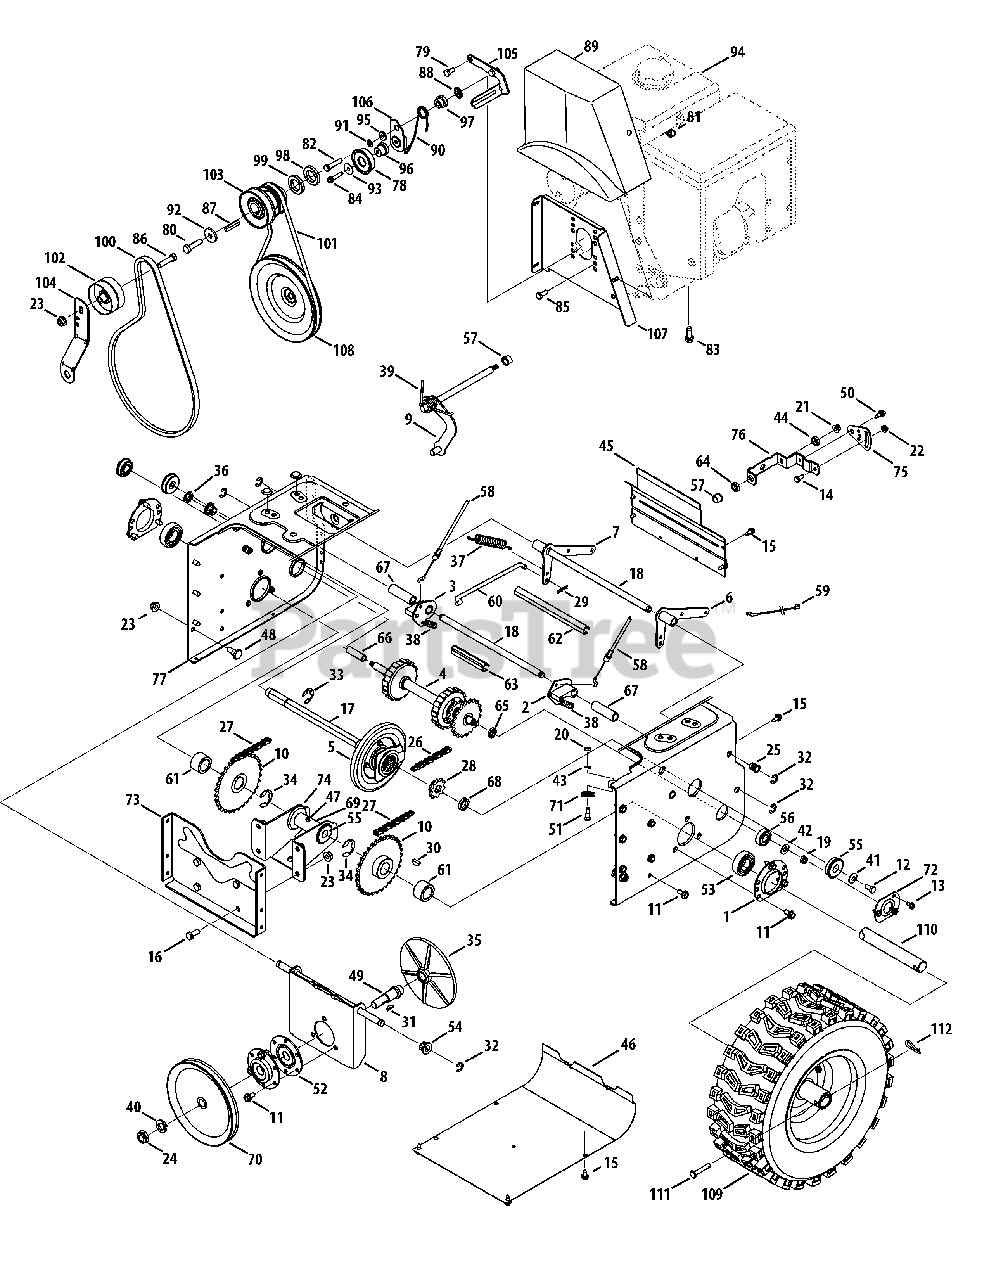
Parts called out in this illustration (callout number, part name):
1	Housing, Bearing
2	Dogg, Steering Drive, LH
3	Dogg, Steering Drive, RH
4	Shaft Assembly, Steering
5	Assembly, Friction Wheel
5	Wheel, Friction, Bonded
5	Screw, Hex Wash
6	Bracket, Auger Actuator
7	Bracket, Drive Actuator
8	Brkt, Friction Drive Suprt.
9	Rod Assembly, Shift
10	Sprocket, 32T
11	TT Screw, 5/16-18 x .750
12	Screw, Hex Cap Lock,
13	1/4-20 x .50
14	Hex Head Screw, 1/4-20
15	Screw, Hex Wash.
16	Screw, Hex Cap, 3/8-16
17	Shaft, Hex Drive
18	Shaft, Actuator
19	Nut, Hex Insert Jam Lock
20	Nut, Hex, 1/4-28 GR5
21	Flange Lock Nut, 5/16-18
22	Flange Lock Nut, 1/4-20
23	Flange Lock Nut, 3/8-16
24	Hex Nut, 5/8-18
25	Nut, Insert 3/8-16
26	Chain, Endless, #41 x 36L
27	Chain, #420 x 40L
28	Sprocket, #41 x 10T
29	Pin, Internal Cotter
30	Key, Woodruff
31	Key, Hi-Pro, 3/16 x 5/8
32	E-Ring
33	Ring, Retaining
34	Ring, Retainer
35	Plate, Drive
36	Speed Nut, .500
37	Spring, Extension
38	Spring, Extension
39	Torsion Spring, .750 I.D. x .968 Lg.
40	Washer, Lock, 5/8
41	Wsh, Bell., .34 x .872 x .06
42	Wash, .406 x .875 x .059
43	Washer, Lock, 1/4
44	Flat Washer, .469 x .875 x .105
45	Cover, Upper Frame
46	Cover, Lower Frame
47	Fitting, Lube, 3/16 Drive
48	Screw, Shldr., .498 x .34
49	Spindle, Drive Plate
50	Shoulder Screw, .368 x .113, 1/4-20
51	Screw, Hex Shldr., 1/4-28
52	Ass’y, Bearing/Housing
53	Bearing, Self Aligning
54	Bearing, Hex Flange
55	Bearing, Ball
56	Bush, Flg, .5625 x 1.375 x .4375
57	Bush, Flg, .5 ID x .627 OD
58	Steering Cable, 35.97" Long
59	Cable, Auger Idler
60	Rod, Drive Clutch
61	Spcr., 1.0 ID x 1.50 OD
62	Spcr., .51 ID x 7.895 Lg.
63	Spcr., .51 ID x 3.66 Lg.
64	Spcr., .5151 ID x .750 OD x .220
65	Spcr., .566 ID x .87 OD x .190
66	Spcr., .566 ID x .87 OD x 1.25
67	Spcr., .514 x .632 x 2.44
68	Spacer, .675 x 1.0 x .23
69	Spcr, .6725 x 1.125 x 2.48
70	Pulley, Auger
71	Roller, Cable
72	Bearing Retaining Bracket
73	Bracket, Frame Support
74	Bracket, Axle Support
75	Speed Selector Pivot Bracket
76	Speed Selector Shift Bracket
77	Transmission Frame
78	Idler Pulley Assembly
79	Screw, Hex Cap, 5/16-24
80	Hex Hd. Screw, 3/8-24 x 1.25 GR8
81	Screw, Hx Wash Hd Tapp
82	Screw, Hex Cap, 5/16-24 x 1.50
83	Screw, 3/8-16 x 1.00
84	Screw, 1/4-20 x 1.25
85	Hex Head Screw, 5/16-24 x .875
86	Hex Head Screw, 3/8-16 x 1.75
87	Square Key, 3/16 x 1.00
88	Nut, Push
89	Cover, Belt
90	Torsion Spring, .850 dia. x .333 lg.
91	Washer, Lock, 5/16
92	Washer, Flat, .406 x 1.25
93	Washer, Flat, .265 x 1.0 x .030
94	Engine Complete
95	Shoulder Spacer, .3175 x .500 x .094
96	Shoulder Spacer, .260 x .785 x .538
97	Shoulder Spacer, .340 x 1.00
98	Spacer, 1.155 ID x 1.78 OD x .150
99	Spacer, 1.004 ID x 1.625 OD x .50
100	V-Belt, 4L x 44.60 Lg.
101	V Belt, 3/8 x 36.68
102	Pulley, Flat Idler, 2.75 OD
103	Double Pulley, 3.25 x 2.75
104	Bracket, Auger Idler
105	Belt Keeper Bracket
106	Idler Drive Wheel Bracket
107	Belt Cover Bracket
108	Pulley, Drive
109	Wheel Ass’y. - LH
109	Wheel Ass’y. - RH
109	Valve
109	Bearing
110	Axle, Wheel, 33"
111	Pin, Clevis
112	Pin, Internal Cotter
